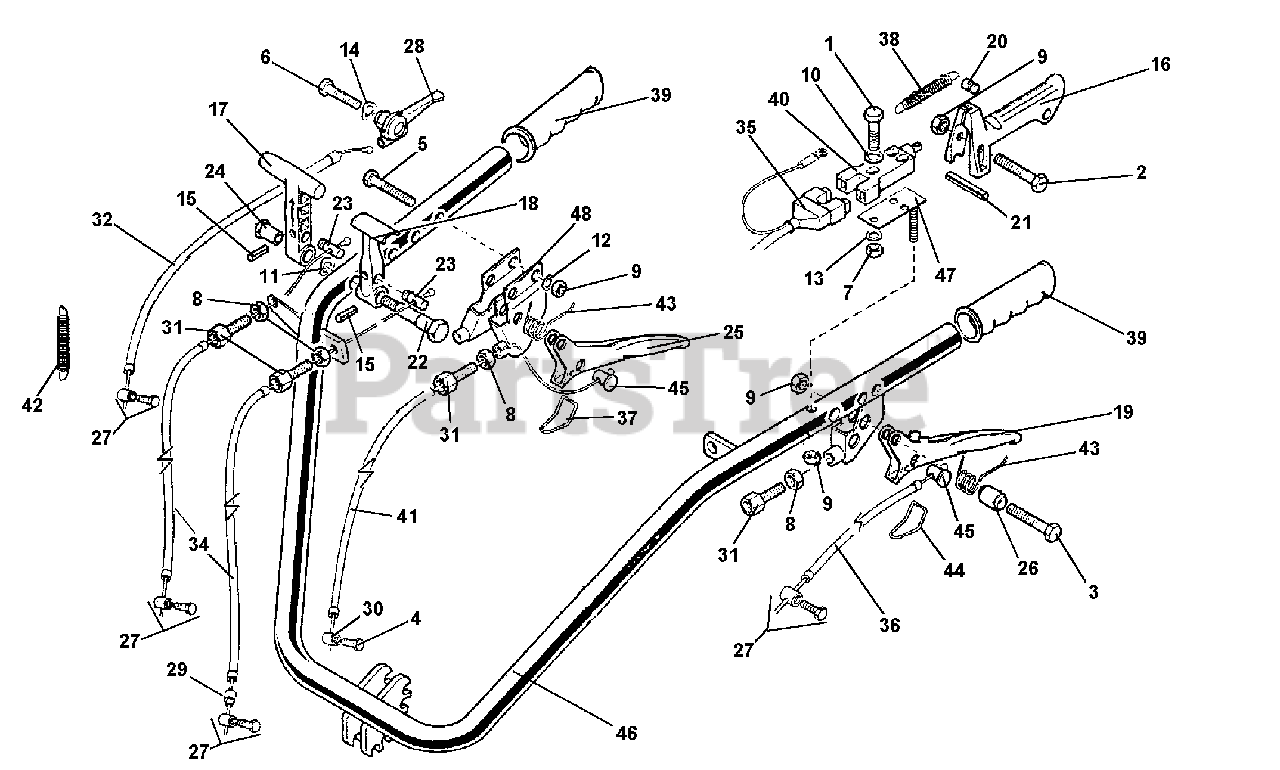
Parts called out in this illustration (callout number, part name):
1	SCREW, M4X25
2	SCREW, M6X45
3	SCREW, M6X25
4	SCREW, M6X16
5	SCREW, M6X35
6	SCREW, M8X35
9	NUT, SELF LOCKING, M6
10	FLAT WASHER, M4.3
12	WASHER, LOCK, M6.4
13	LOCK WASHER, M4.3
14	WASHER, LOCK, M8.4
15	PIN, LOCKING, M4X20
16	MOTOR STOP LEVER
17	REVERSER LEVER
18	LEVER DIFFERENTIAL LOCKING
19	CLUTCH LEVER
21	LEVER STOP FOR MOTOR STOP
23	DRILLED PIN
24	DRILLED PIN
26	LEVER SPACER
27	CLAMP, CABLE
28	LEVER, ACCELERATOR
30	PIN, CABLE CLAMP
31	SCREW, ADJUSTING M8
32	THROTTLE CABLE, KOHLER
33	CABLE, REVERSE
34	CABLE, DIFFERENTIAL
35	SWITCH WIRING HARNESS
36	CLUTCH CABLE
40	STOP SWITCH
41	CABLE, BRAKE
42	SPRING, KOHLER
43	LEVER SPRING
46	HANDLE ASSEMBLY
47	SWITCH PLATE
48	COUPLING FOR DOUBLE LEVER
